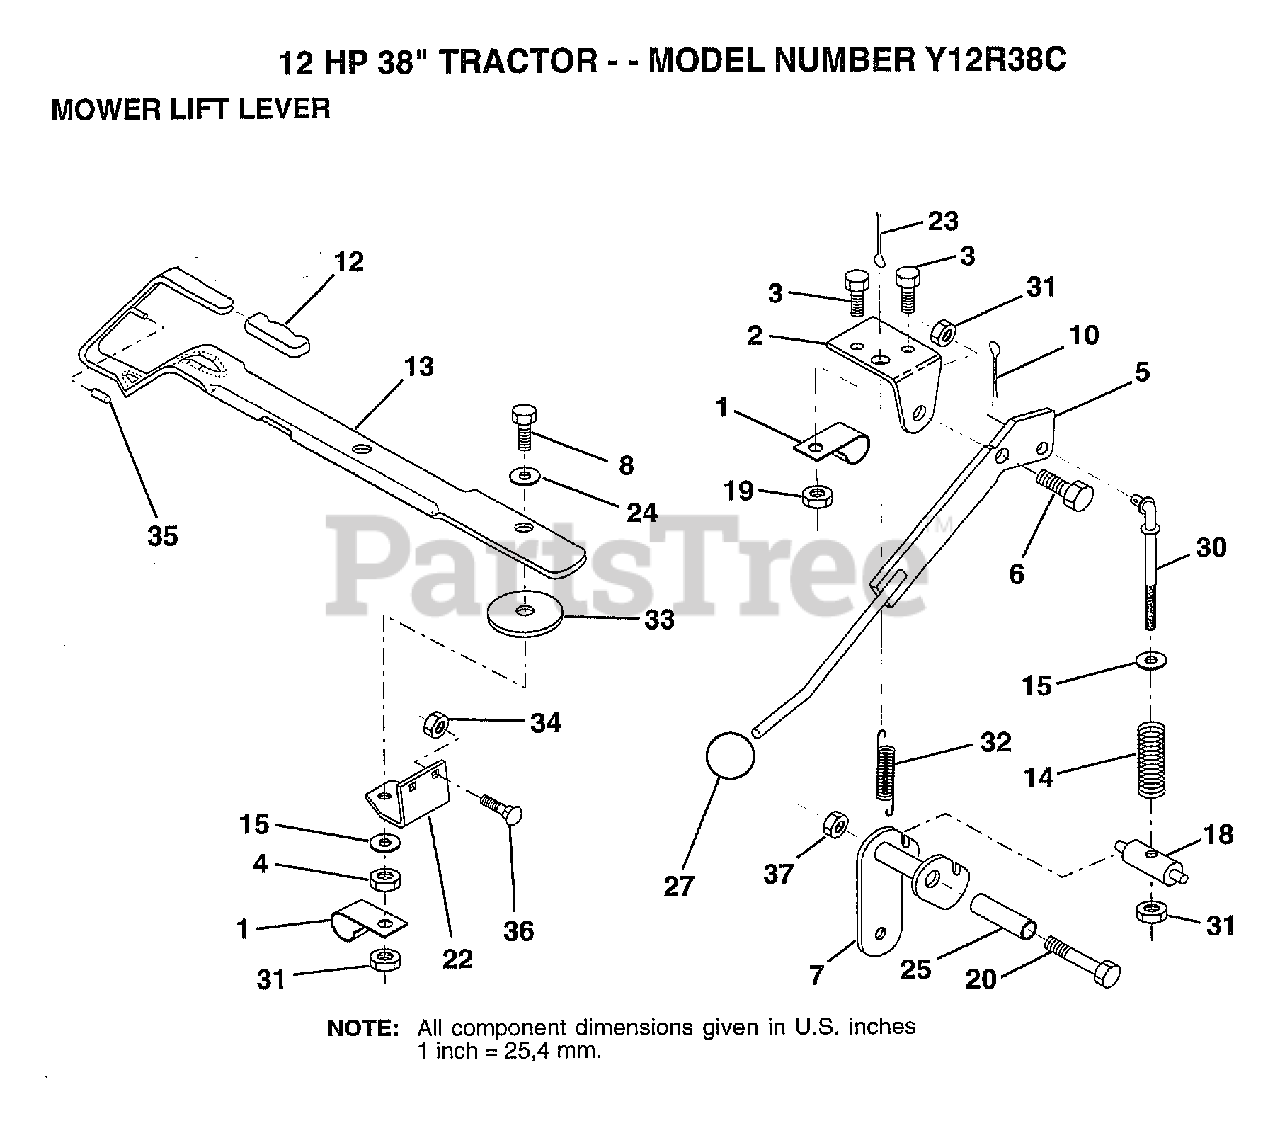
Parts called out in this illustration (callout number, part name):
1	"CLIP,INSULATOR"
2	BRKT CLUTCH
3	BOLT
4	NUT
5	CLUTCH LEVER AS
6	"BOLT, SHOULDER LT"
7	ARM.CLUTCH.ASM
8	BOLT
10	COTTER PIN
12	GRIP HANDLE
13	LEVER LIFT LR
14	COMP CLUTCH SPRNG
15	WASHER HYT
18	TRUNNION
20	BOLT
22	LIFT LEVER BRKT
24	WASHER
25	TUBE SPACER
27	KNOB
30	ROD TENSION CLUTC
31	NUT
32	SPRING EXT
33	WASHER
34	NUT
35	VINYL CAP RED
36	BOLT
